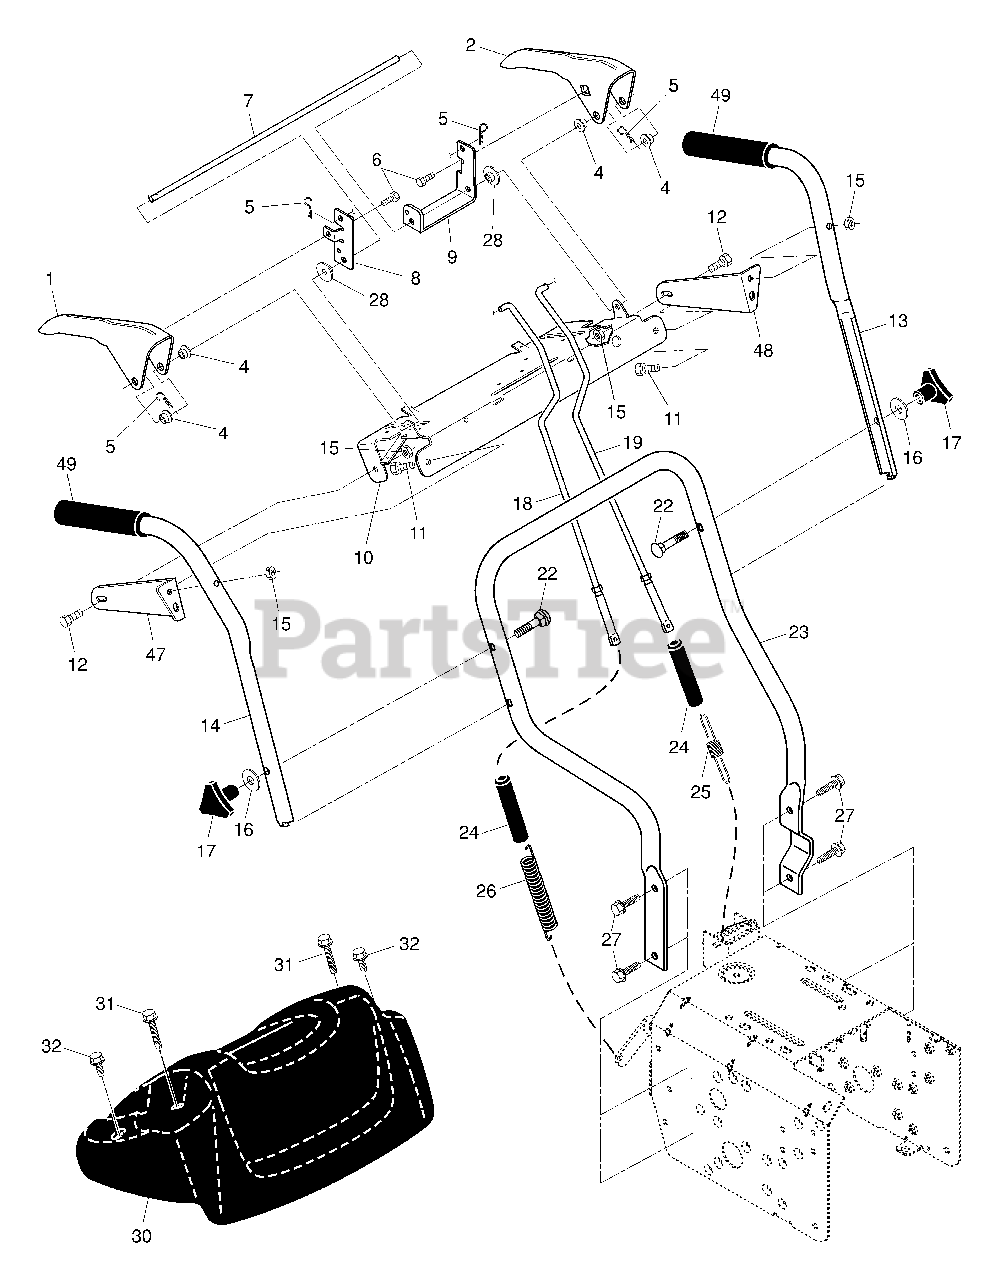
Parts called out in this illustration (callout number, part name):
1	Lever, Auger Control, RH
2	Lever, Traction Drive Control, LH
4	Bushing, Flange
5	Retainer, Hairpin
6	Screw, Hex Head
7	Rod, Interlock
8	Arm, Impeller Rod
9	Arm, Traction Rod
10	Panel, Control
11	Screw, Hex Head 5/16-18 x 1-1/2
12	Screw, Hex Head 5/16-18 x 1-3/4
13	Handle Tube, LH
14	Handle Tube, RH
15	Nut, Lock 5/16-18
16	Washer, Flat 3/8
17	Knob, Handle
18	Rod, Auger Control
19	Rod, Traction Control
22	Bolt, Carriage 3/8-16 x 2-1/4
23	Handle Tube, Lower
24	Sleeve, Spring
25	Spring, Traction Drive
26	Spring, Auger Control
27	Screw, Hex Head 3/8-16 x 1
28	Bushing, Pivot Lever
30	Console, Panel
31	Screw, Hex Head, Tapping #10-24 x 1-1/4
32	Screw, Hex Head, Tapping #10-24 x 1/2
36	Spring, Torsion
47	Mounting Bracket, Handle, LH
48	Mounting Bracket, Handle, RH
49	Grip, Handle
